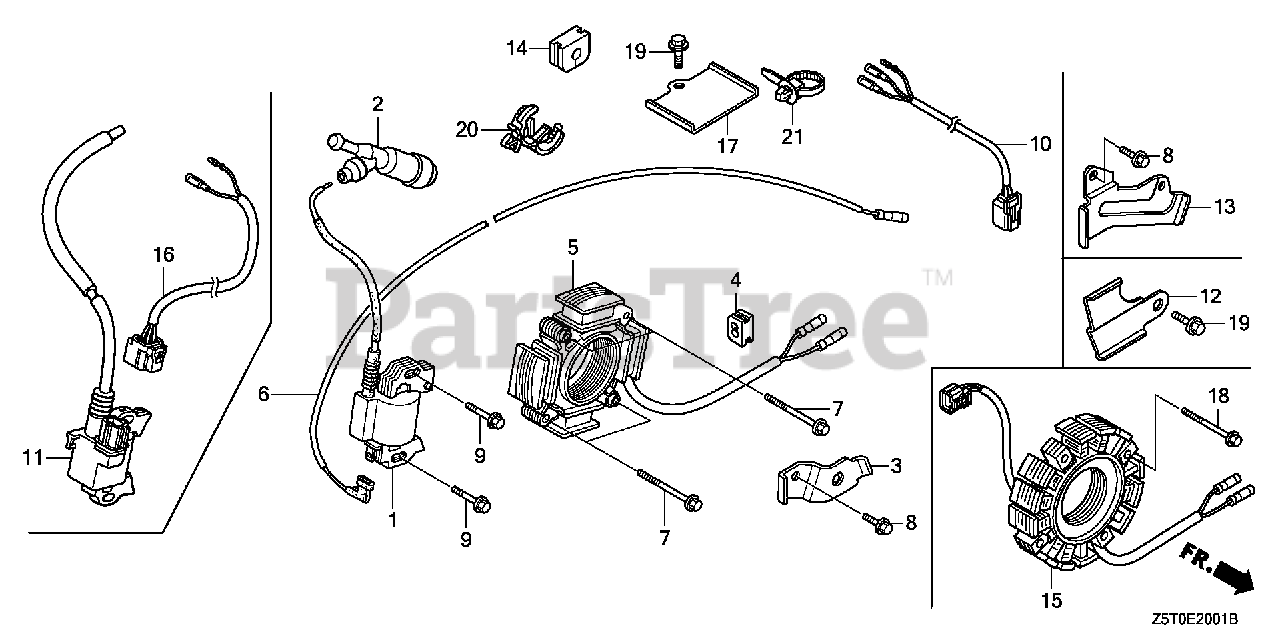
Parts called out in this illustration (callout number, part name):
2	CAP ASSY., NOISE SUPPRESSOR (NGK Y-EZD)
3	CLAMP, WIRE
4	GROMMET, WIRE
5	COIL ASSY., CHARGE (12V-17A)
7	BOLT, FLANGE (6X40)
8	BOLT, FLANGE (6X12) (CT200)
9	BOLT, FLANGE (6X28) (CT200) Use up to Engine SN 1530314.
10	WIRE HARNESS ASSY., ENGINE (SEL)
11	COIL ASSY., IGNITION
11	COIL ASSY., IGNITION (IIDA)
